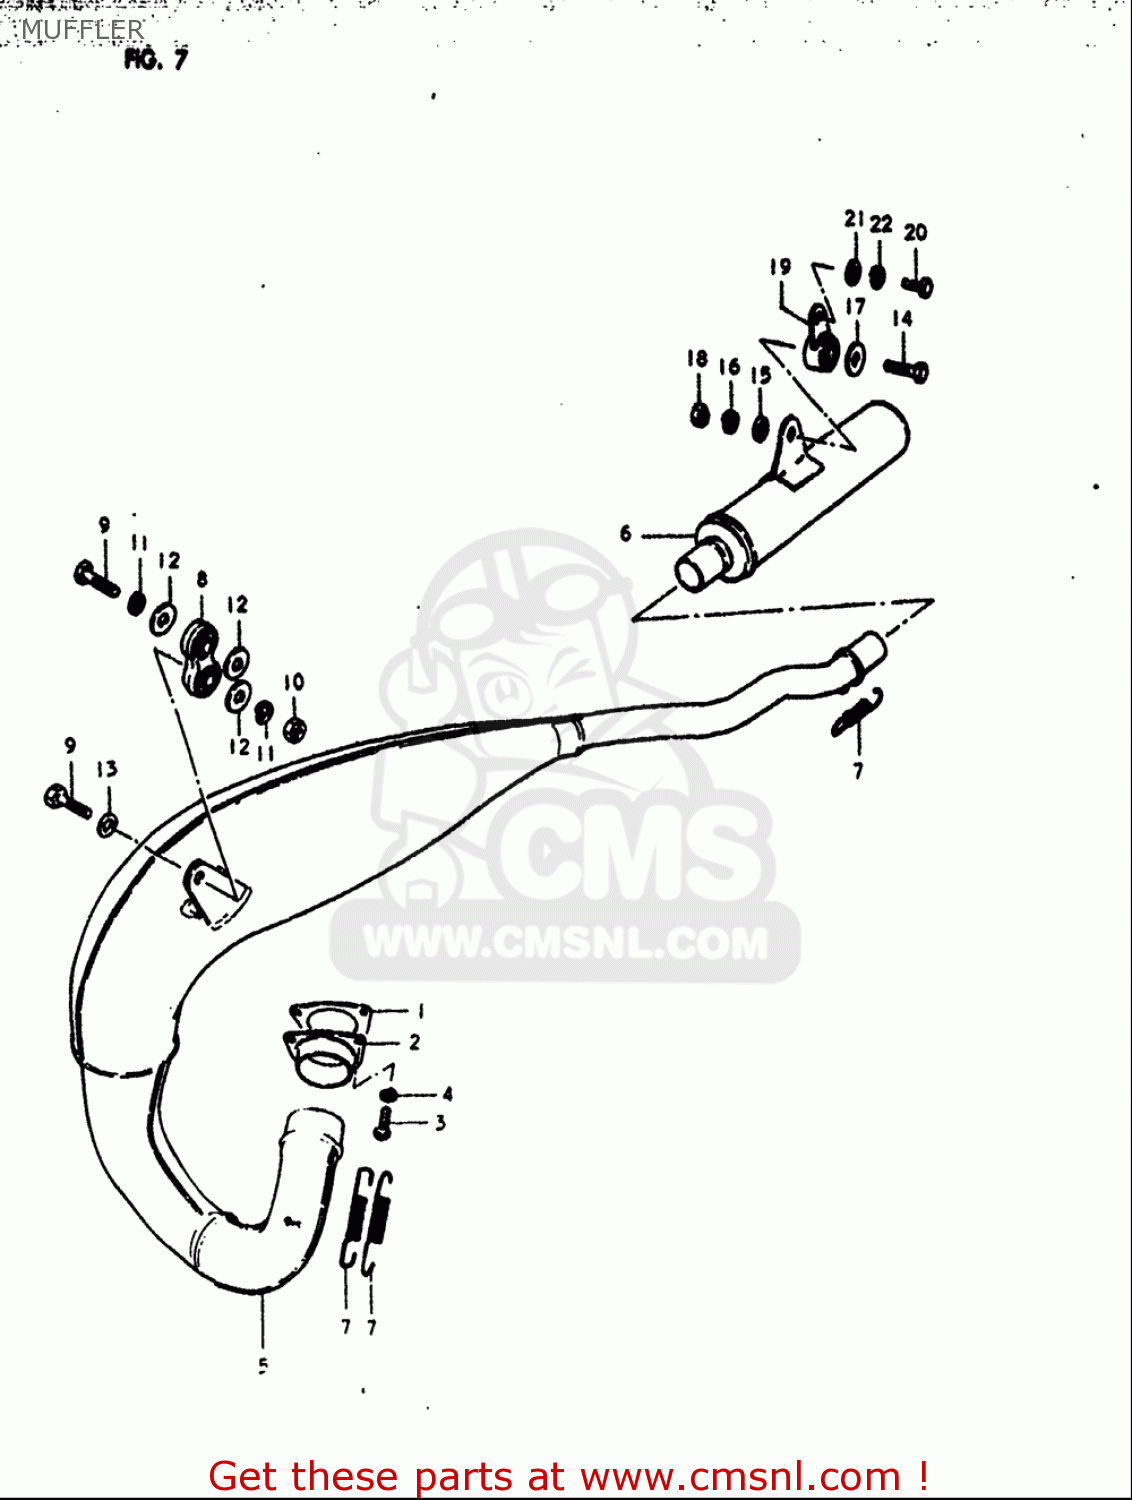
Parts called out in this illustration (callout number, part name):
1	GASKET,EXHAUST FLANGE (NAS)
3	SCREW
4	WASHER,LOCK
6	BODY,MUFFLER,SECOND
7	SPRING
8	DAMPER,MUFFLER
9	BOLT
10	NUT
11	WASHER,LOCK
12	WASHER(8.5X24X1.6)
13	WASHER
14	BOLT
15	WASHER
16	WASHER,LOCK
17	WASHER(8.5X28X1.6)
18	NUT
19	DAMPER,MUFFLER SUPPORT 2ND
20	BOLT
21	WASHER
22	WASHER,LOCK
